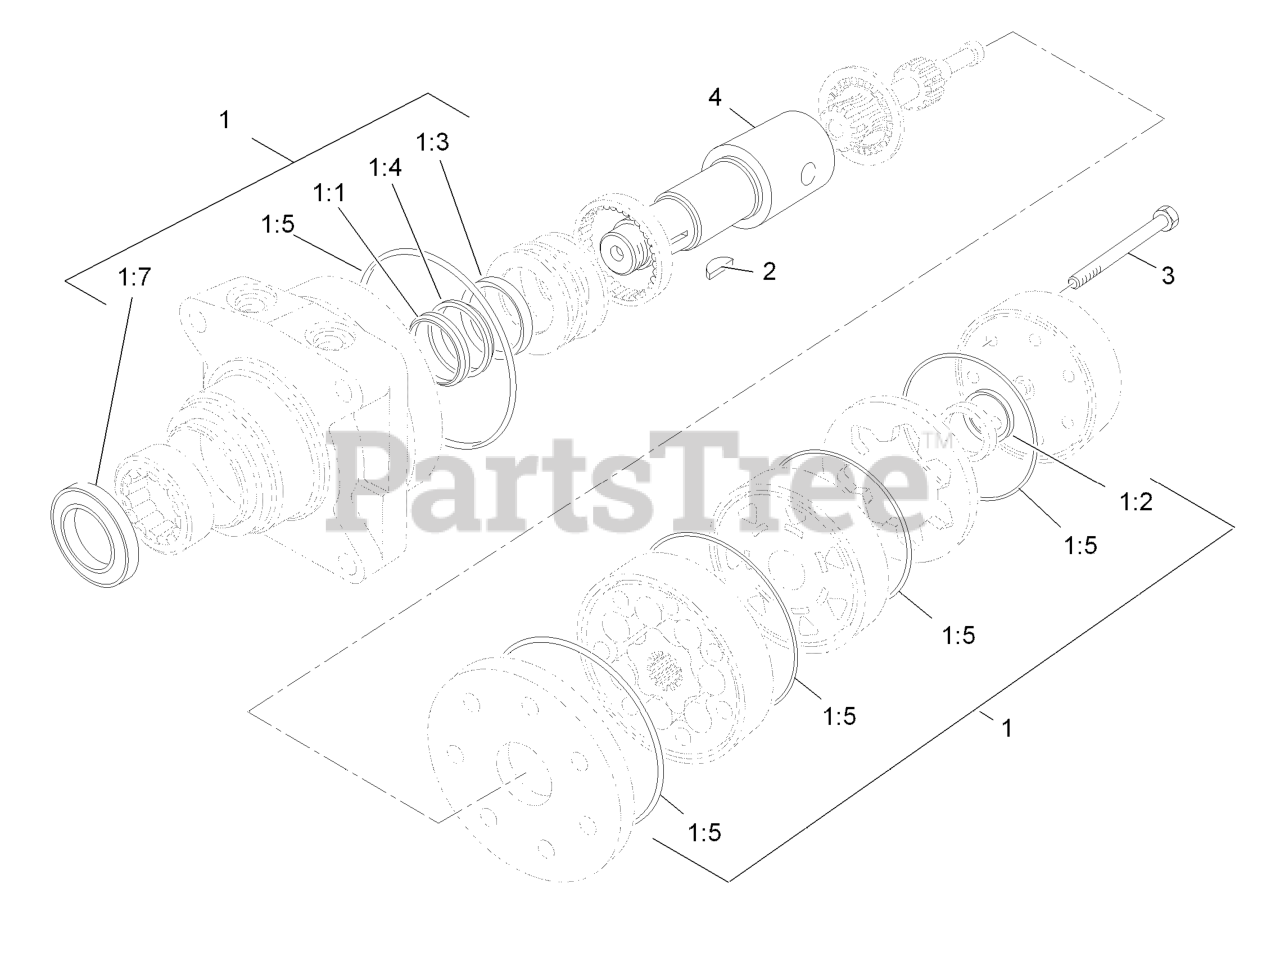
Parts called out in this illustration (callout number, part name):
1	SEAL KIT
1:1	Ring-Back Up
1:2	Seal-Commutator
1:3	Seal-Shaft (Viton)
1:4	Washer-Back Up, Steel
1:5	Ring-Seal (Viton)
1:7	Seal-Dirt And Water
2	KEY-WOODRUFF
3	BOLT-SPECIAL
4	SHAFT-COUPLING
